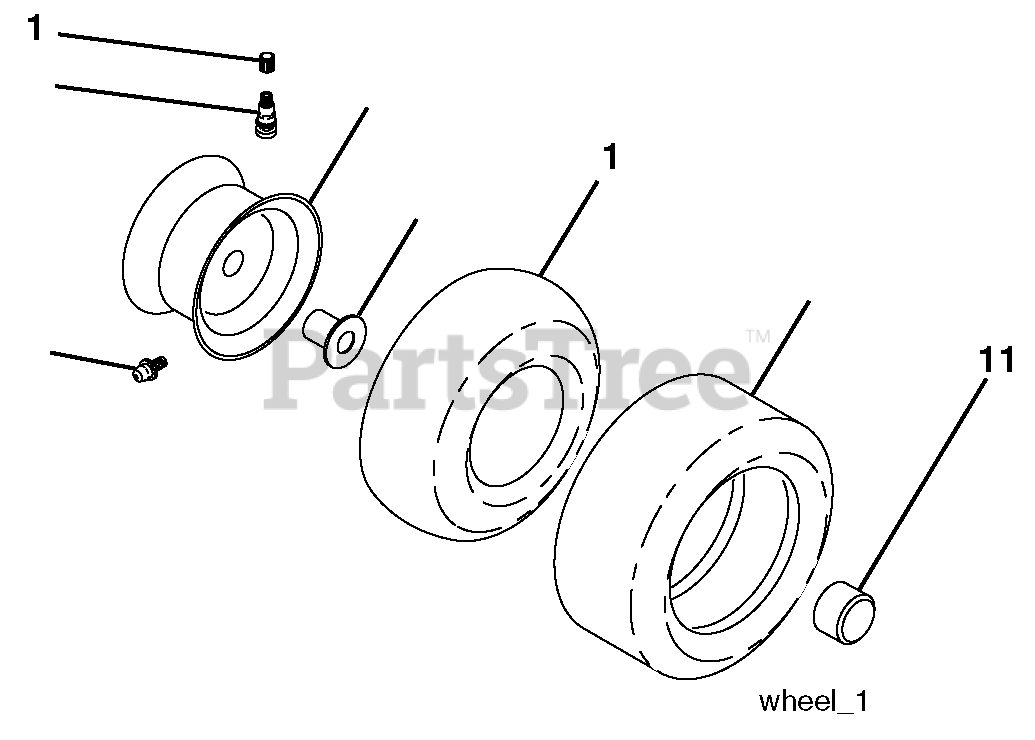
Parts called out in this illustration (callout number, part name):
1	Cap, Tire valve
2	Stem, Valve
4	Tube, Front
5	Rim assembly, 6"front
6	Fitting, Grease
7	Bearing, Flange
8	Rim assembly, 8" rear
9	Tire, Rear
10	Tube, Rear
11	Cap, Hub Axle
11	Sealant, Tire (10 oz. Tube)
